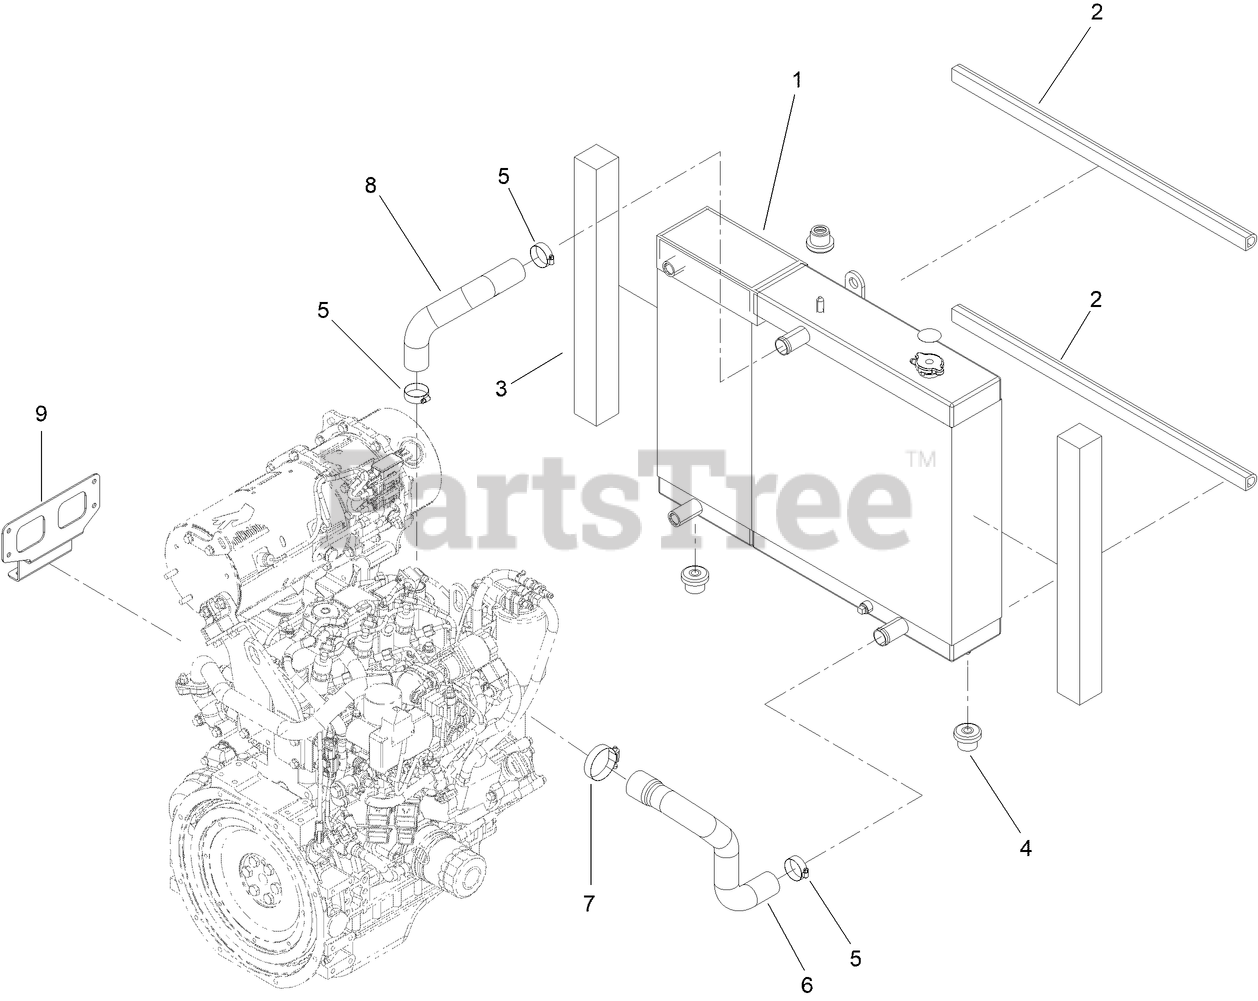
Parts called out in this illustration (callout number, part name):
1	COOLING ASM
2	RUBBER SEAL
3	SEAL-FOAM
4	MOUNT-ISOLATOR
5	CLAMP-HOSE
6	HOSE-RADIATOR, LOWER
7	CLAMP-HOSE
8	HOSE-RADIATOR, UPPER
9	RES. BRACKET
